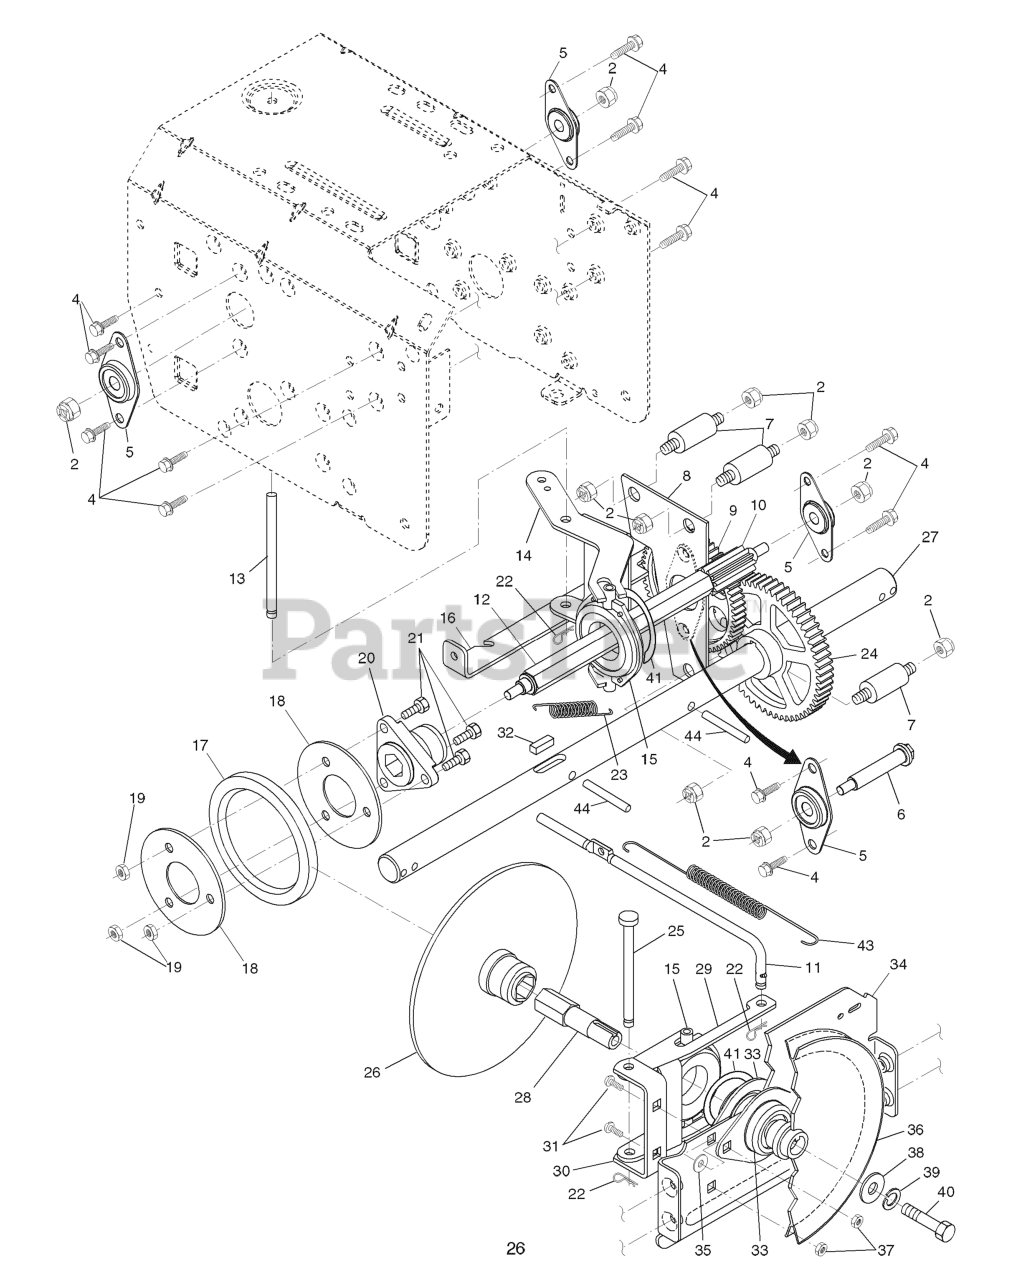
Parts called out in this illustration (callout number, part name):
2	NUT.LOCK.5/16-18
4	Screw, Hex Head 5/16-18 x 1/2
5	BEARING, FLANGE
6	SHAFT, AUXILIARY
7	SPACER, PLATE
8	AUXILLARY PLATE
9	GEAR, INTERMEDIATE
10	GEAR, PINION
11	ROD.CLUTCH.YELLOW.ZINC
12	SHAFT.HEX.LONG
13	Pin, Pivot
14	LEVER, SPEED CONTROL
15	TRUNNION BEARING ASSY
16	BRACKET, PIVOT, SHIFT
17	RING, RUBBER WHEEL
18	PLATE.RUBBER.WHEEL
19	NUT.CENTERLOCK.5/16-
20	HUB, RUBBER WHEEL
21	BOLT
22	RETAINER CLIP PM
23	SPRING, BIAS
24	GEAR, AXLE (58T)
25	PIN, PIVOT LEVER
26	DRIVE PLATE WELDMENT
27	AXLE.ASM.SHAFT.W/ROLLPIN.PS
28	SHAFT.HEX.SHORT
29	LEVER.SHIFTER.PLATE.BLACK
30	BRACKET, SHIFTER SUPPORT
31	BOLT
32	KEY, SQUARE 1/4 X .875
33	BEARING FLANGE
34	PLATE.DRIVE.MOUNTING.BLACK
35	SPACER, BEARING
36	PULLEY.TRACTION.7.75
37	NUT.FLANGE.5/16
38	WASHER, FLAT
39	WASHER.LOCK.HVY.HLCL.SPR.5/16
40	Screw, Hex Head 5/16-18 x 3/4
41	RETAINING RING (2 2)(3 2)
43	SPRING.RETURN
44	PIN.ROLL.3/16
